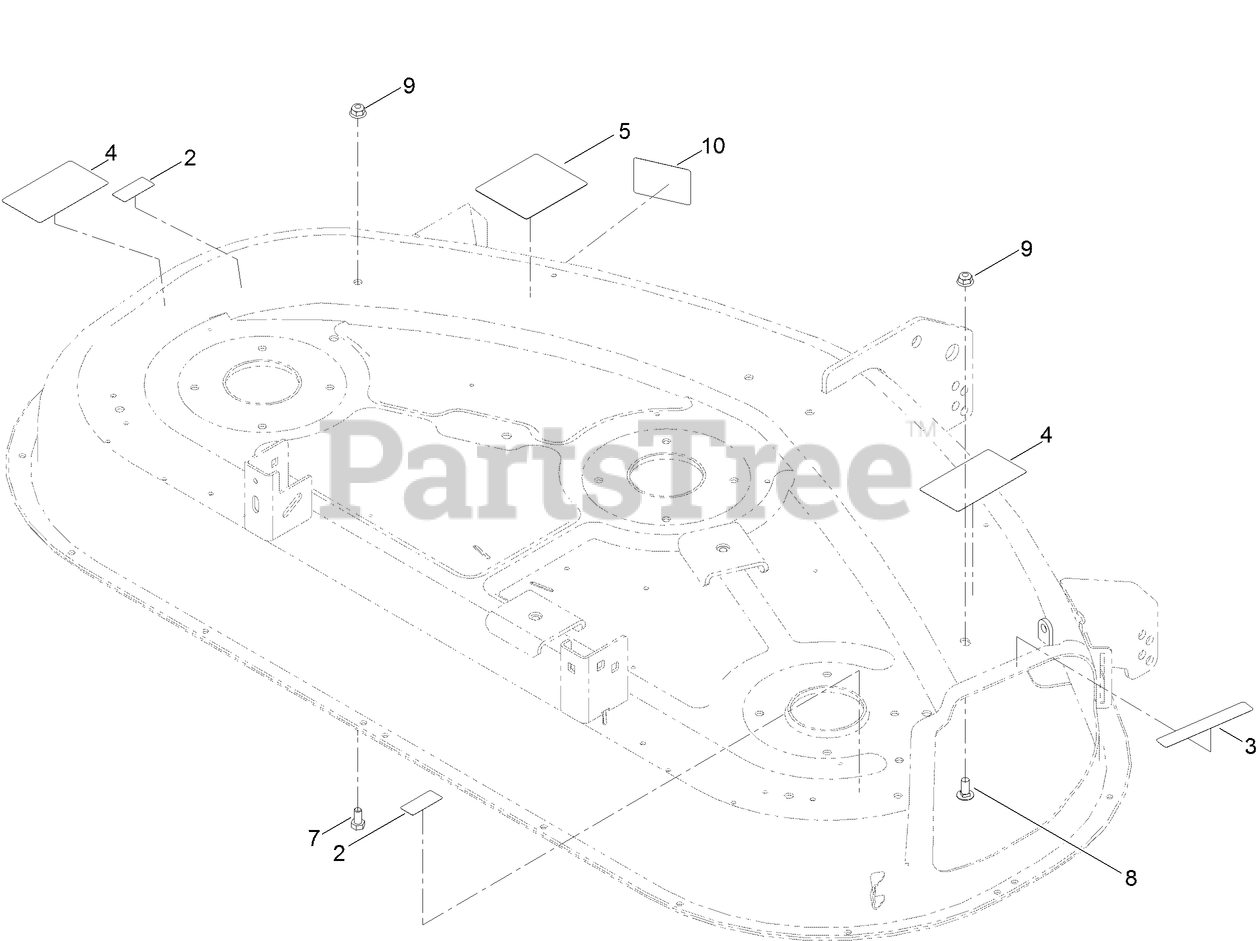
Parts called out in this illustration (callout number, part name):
2	DECAL-DANGER
3	DECAL-DANGER
4	DECAL-DANGER
5	DECAL-ROUTING, BELT
7	SCREW-HH
8	SCREW-CARR
9	NUT-HF, NI
10	DECAL-SCALP, ANTI
